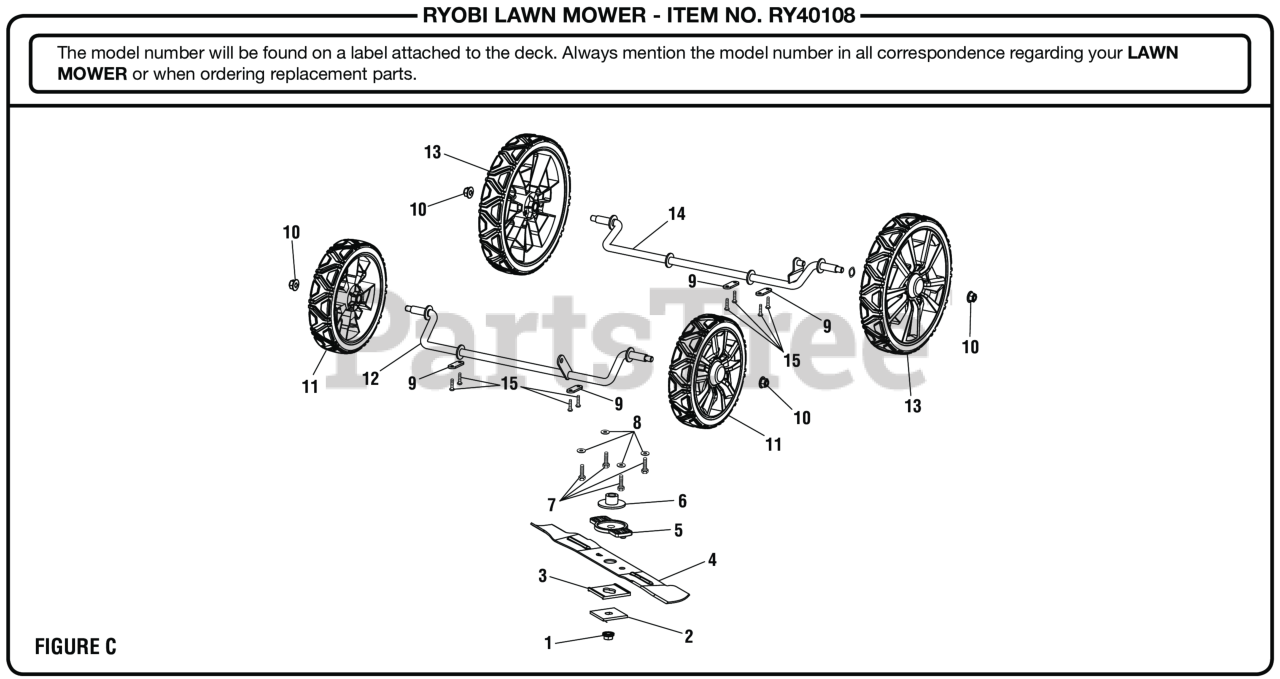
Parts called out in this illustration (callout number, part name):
1	Blade Nut (M10 x 1.25, Hex Flange Hd.)
2	Metal Blade Retainer
4	Bagging Blade
5	Motor Fan Blade Adapter
6	Motor Shaft Bushing
7	Bolt (M6 x 26 mm, Hex Hd.)
8	Washer (ID6.2 x OD15 x 0.08t)
9	Axle Pressure Plate
10	Flange Lock Nut (M8 x 1.25 mm)
11	Front Wheel Assembly
12	Front Axle
13	Rear Wheel Assembly
14	Rear Wheel Axle
15	Screw (M4 x 20 mm, T20 Torx Pan Hd. S.T.)
